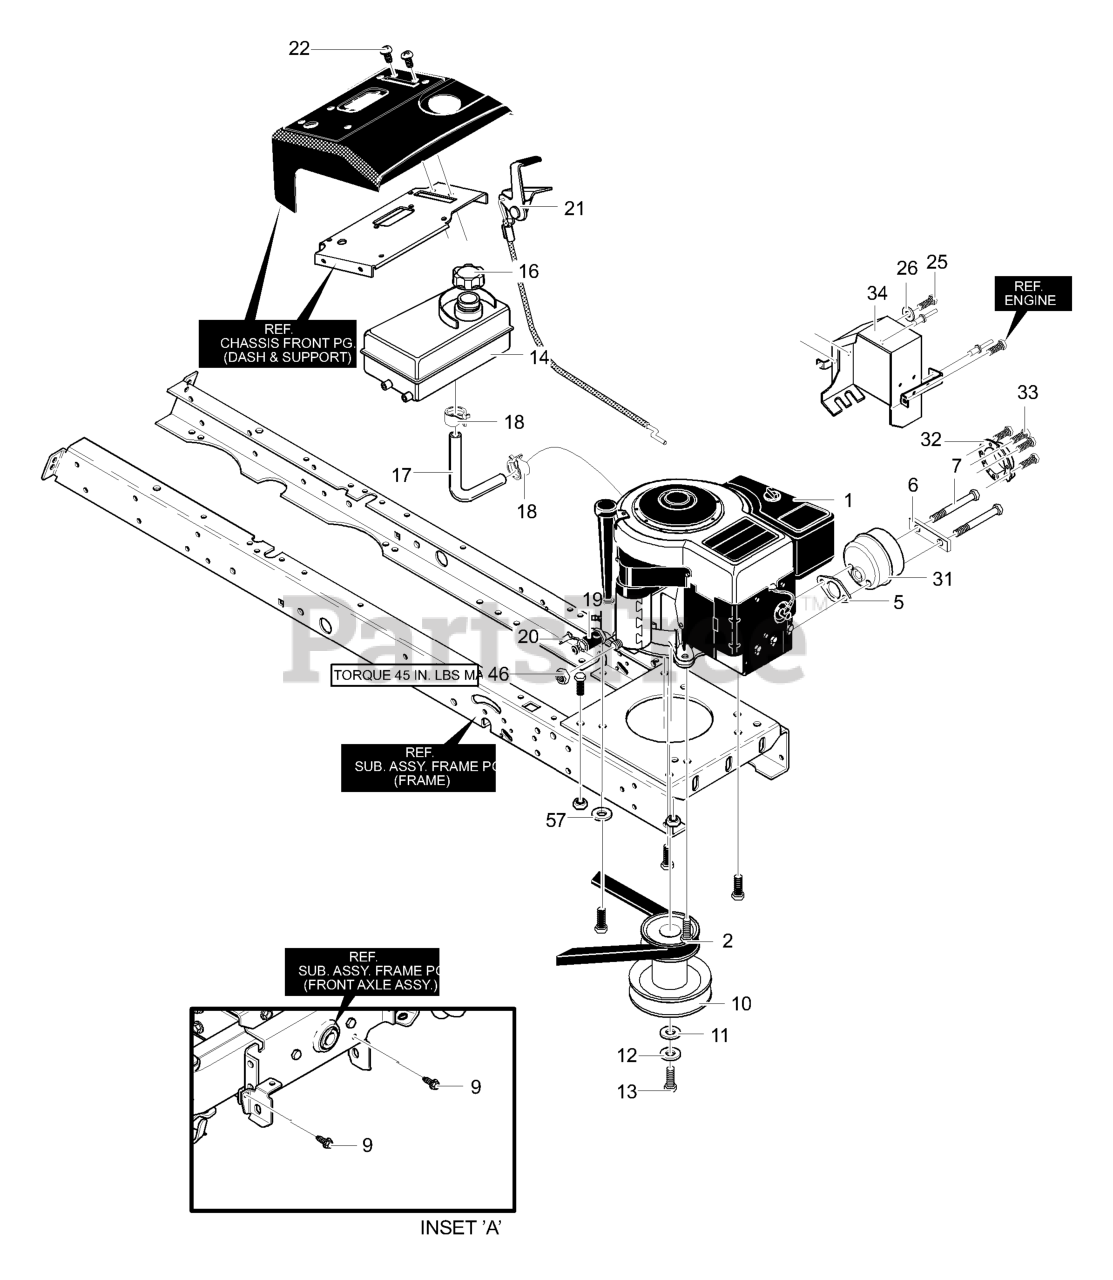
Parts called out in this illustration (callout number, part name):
1	ENGINE
2	BOLT
5	GASKET, Exhaust
6	BRACKET, LOCK
10	PULLEY, STACK
12	WASHER
14	TANK, FUEL
16	FUEL CAP
17	TUBING, GAS
18	CLAMP, FUEL LINE
19	OIL DRAIN VALVE ASSEMBLY
20	CAP, OIL DRAIN VALVE
21	CONTROL, THROTTLE
26	WASHER
31	MUFFLER
32	DEFLECTOR, EXHAUST
34	SHIELD, HEAT
57	WASHER
